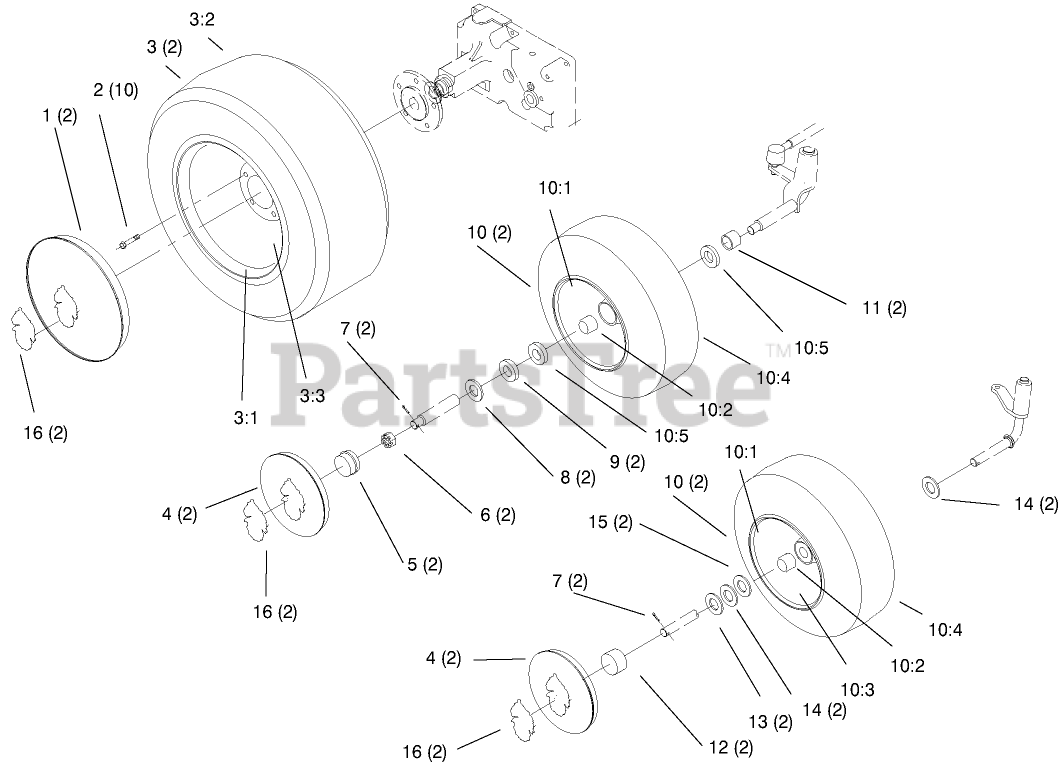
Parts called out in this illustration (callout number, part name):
2	BOLT-LUG
3	ASM-Wheel Tire
3:1	WHEEL
3:3	VALVE
7	PIN-COTTER
10:3	VALVE
10:5	SEAL-OIL
12	HUBCAP
13	WASHER WHEEL
14	WASHER
15	WASHER-SHIM
